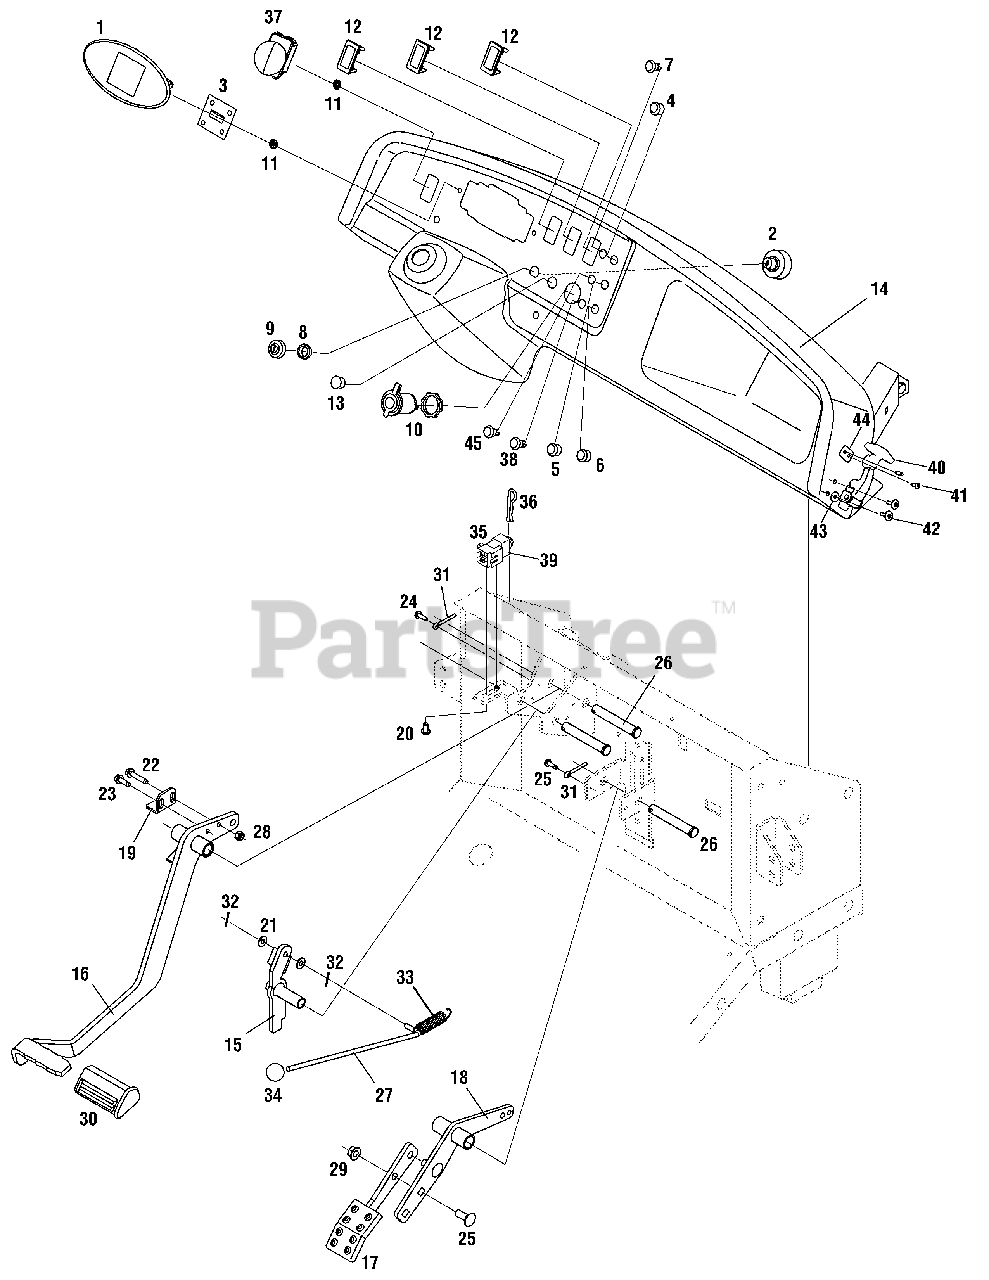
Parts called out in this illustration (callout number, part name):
1	Instrument Cover
2	Switch, Key
3	Meter, Hour
4	Switch, Green
5	Switch, Yellow
6	Switch, Red
7	Light, Ind., Green
8	Nut, Ignition Switch, 5/8-32
9	Cap, Ignition Switch
10	Power Receptacle, 12V
11	Nut, Retainer, 1/8
12	Panel, Plug, Switch
13	Plug, Horn Switch
14	Dash Panel
15	Lever , Parking Brake
16	Pedal Assembly, Brake
17	Pedal Assembly, Throttle
18	Pedal Arm Assembly, Throttle
19	Plate, Brake Switch
20	Screw, Hi-Lo, 1/4-20 x .5
21	Washer, Flat .25 x .630 x .0515
22	Screw, Self-Tapping, 1/4-20x1.25
23	Screw, Self-tapping, 1/4-20, .75
24	Screw, Self-tapp, #10-32 x .625
25	Bolt, Carriage, 3/8-16 x 1.0
26	Pin, Clevis .50 x 3.25
27	Rod, Brake Lock
28	Nut, Hexlock, 1/4-20 GR 8
29	Nut, Flange Lock, 3/8-16
30	Pad, Brake Pedal
31	Pin, Cotter, 5/32 x 1.0 Lg.
32	Pin, Cotter, 1/16
33	Spring, Extension, .637 x 2.972
34	Knob, Ball
35	Snap Mount Switch, Interlock
36	Pin, Cotter.08 x 1.42
37	Differential Lock Switch
38	Light, Ind., Yellow
39	Cvr., Protective
40	Hndl, Latch
41	Rivet, Pop, 3/16 Dia.
42	Rivet, Pop, .188 Dia.
43	Wash., Fl, .194 x .62 x .063
44	Plt., Mnt., Hood
45	Light, Ind., Red
